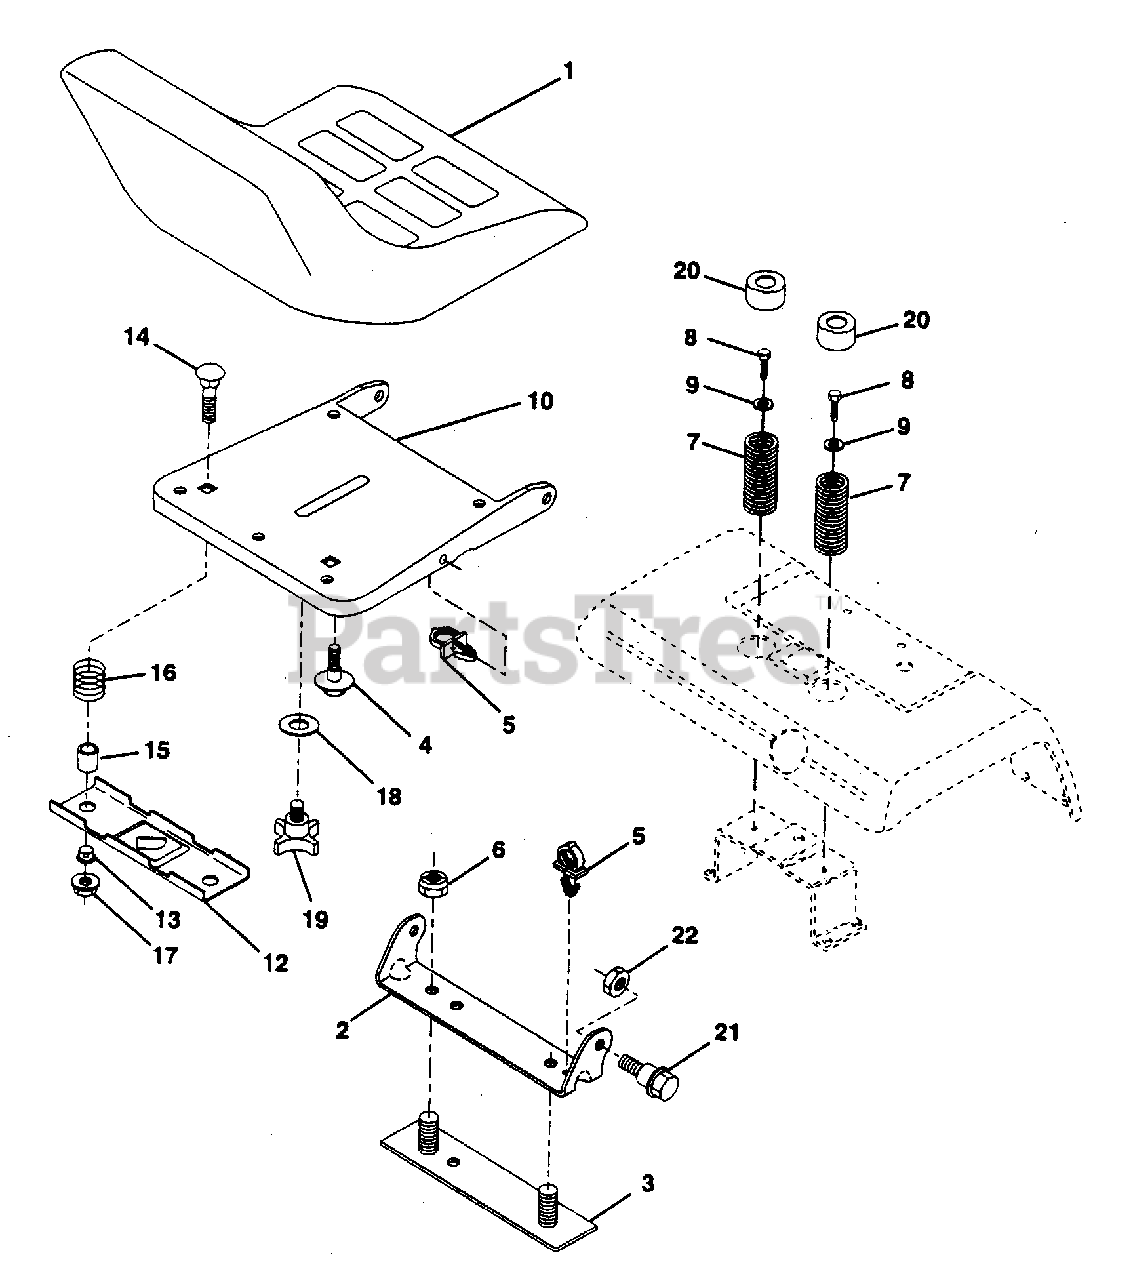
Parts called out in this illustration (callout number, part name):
1	Seat (AYP part number)
2	Bracket, Pivot Seat (AYP part number)
3	Strap, Fender (AYP part number)
4	Bolt, Shoulder 5/16-18 X .62 (AYP part number)
5	Clip, Push In Hinged (AYP part number)
6	Nut, Crownlock 3/8-16 Unc
7	Spring, Seat Cprsn (AYP part number)
8	Screw, Thdrol 5/16-18 X 1/2 (AYP part number)
9	Washer 13/32 X 1 X 14 Ga. (AYP part number)
10	Pan, Seat (AYP part number)
12	Bracket, Mounting Switch (AYP part number)
13	Bushing, Snap (AYP part number)
14	Bolt, Carriage 1/4-20 X 1-3/8
15	Spacer, Split (AYP part number)
16	Spring, Cprsn (AYP part number)
17	Nut, Lock 1/4 Lge Flg Gr. 5 (AYP part number)
18	Washer 17/32 X 1-3/16 X 12 Ga. (AYP part number)
19	Knob, Seat 1/2-13 Unc (AYP part number)
20	Cap, Spring Seat (AYP part number)
21	Bolt, Shoulder 5/16-18 Unc (AYP part number)
22	Nut, Crownlock 5/16-18 Unc
